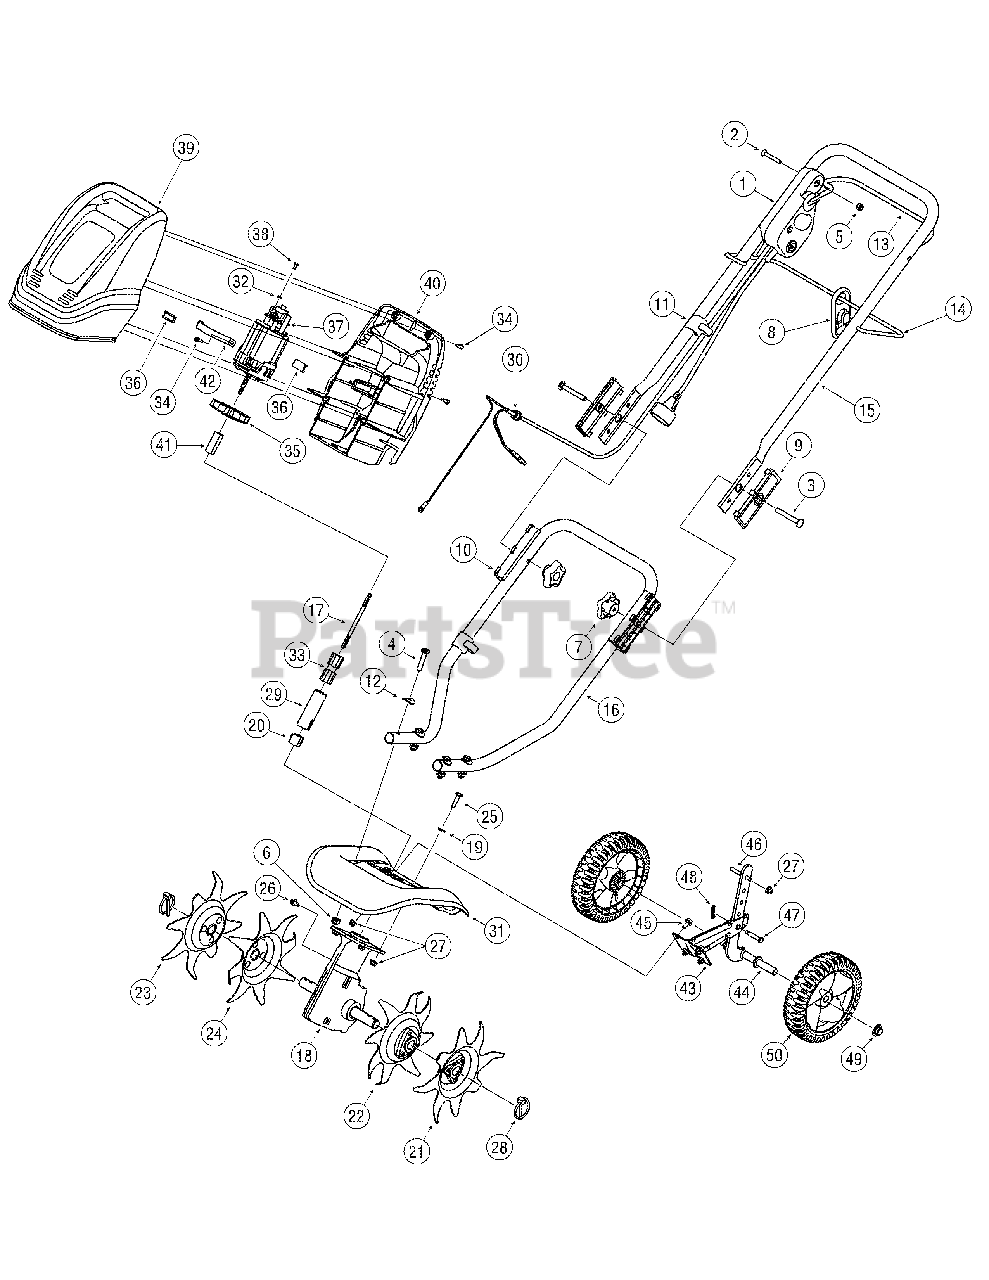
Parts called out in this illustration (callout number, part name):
1	Switch Assembly
2	Screw, T27,1/4-20, 1.75"
3	Bolt, Carriage, 5/16-18, 2.50, Gr1
4	Hex Screw, 5/16-18,1.50, Gr5
5	Nut, Hex Lock, 1/4-20, Gr8, Nylon
6	Nut, Flange Lock, 5/16-18, Gr8, Nylon
7	Knob, Nut, 5/16-18
9	Insulator, Upper Handle
10	Insulator, Lower Handle
11	Guide Cable
12	Washer, Saddle, 320 x .93 x .060
15	Handle, Upper
17	Flex Shaft, 4.5"
18	Gearbox
19	Washer, Flat
21	Tine Assembly, Outer
22	Tine Assembly, Inner
23	Tine Assembly, Outer
24	Tine Assembly, Inner
25	Hex Screw, 1/4-20, 1.00, Gr5
26	Bolt, Hex Washer 1/4-20 x .50
27	Nut, Flange Lock, 1/4-20, GrF, Nylon
28	Lynch Pin,.1875
30	Bushing, Cord
31	Tine Shield
32	Washer, Lock, #10
33	Tube w/ Spacers
34	Screw,.750
35	Fan
36	Motor Pad, 1"
37	Motor Assembly, 120V
38	Screw, #8-32 x .312
39	Motor Cover, Front
40	Motor Cover, Rear
42	Motor Strap
43	Bracket Asesmbly, Tail Piece
44	Support Bracket Assembly, Wheel
45	Hex Flange Screw, 1/4-20,.50,Gr5
46	Belt Guard Pin 1/4 Dia. x 1.43
47	Clevis Pin, .250 x 1.53
48	Cotter Pin,.072 Dia. x 1.13
49	Push Cap, 1/2"
50	Wheel, 7 x 1.8 Spoke Bar Gray
